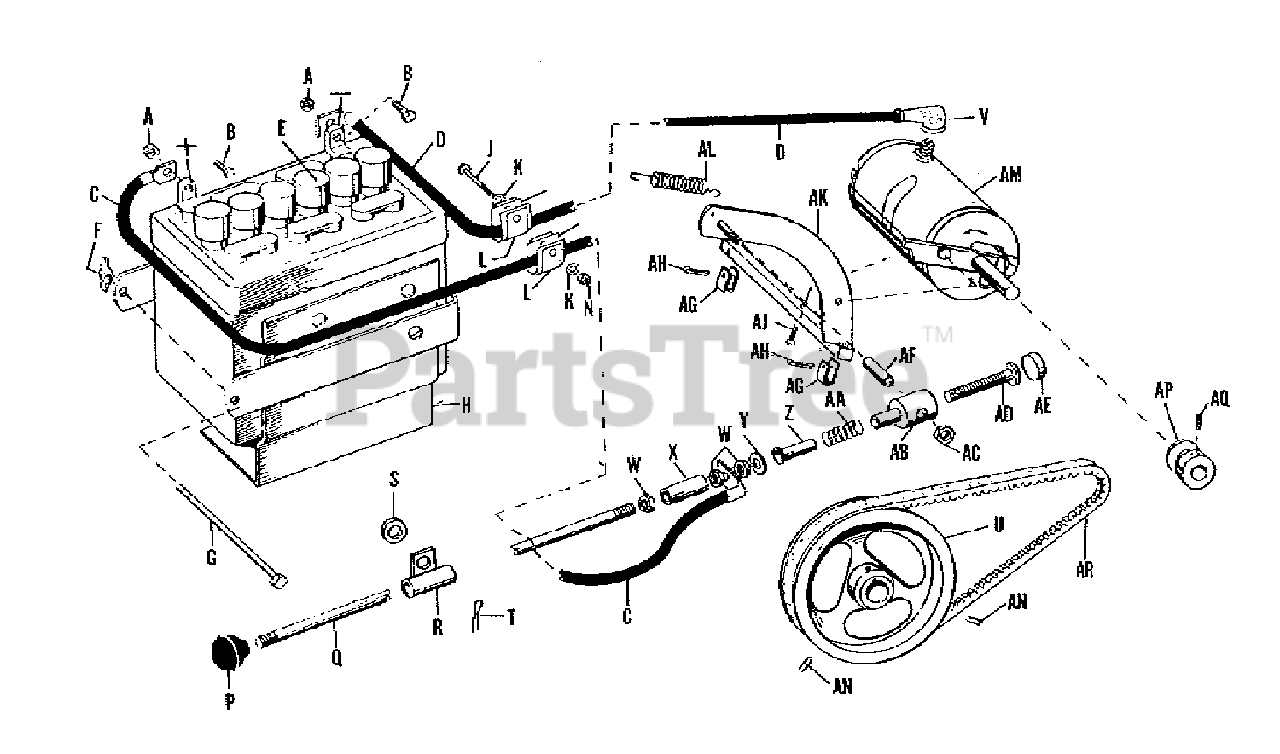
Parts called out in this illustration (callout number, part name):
A	NUT, Hex, Full, 1/4"-20 N.C. Reg.
B	SCREW, Hex Head Cap, 1/4"-20 NC x 5/8 Large
D	CABLE ASSEMBLY
E	BATTERY (PURCHASE FROM BAT. Mfg.)
F	NUT, Wing Lock, 1/4" 20NC
G	BOLT, Machine, 1/4" 20NC x 6" Large
H	BRACKET ASSEMBLY, Battery
J	SCREW, Round Head Machine, #10-24 X 1 1/2" Large
K	WASHER, Plain, 3/16 Standard
L	CLIP, Cable
M	LINING, Clip
N	NUT, Hex Lock, #10-24
P	KNOB, Starter
Q	ROD, Starter
R	GUIDE ASSEMBLY, Rod
S	WASHER, Plain, 3/8" Standard
T	PIN, Cotter
U	PULLEY, Engine
V	COVER, Terminal
W	NUT, Hex. Jam, 5/16"-18NC Reg.
X	INSULATOR
Y	WASHER, Plain, 5/16" Standard
AB	BODY, Switch
AC	NUT, Hex. Lock Full, 5/16-18NC Reg.
AD	BOLT, Contact
AE	PLUG, Switch Body
AG	STRAP, Motor Support
AH	PIN, Cotter
AJ	SCREW, Socket, 3/4"-20NC x 3/4" Large
AK	LEVER ASSEMBLY, Belt Tension
AM	MOTOR, Starter (See Note)
AN	SCREW, Hex. Socket Cup Point Set, 5/16"-18 NC x 1/2" Large
AP	PULLEY, Motor
AQ	SCREW, Hex Socket Cup Point Set, 1/4"-20 NC x 5/16" Large
AR	V" BELT, Starter 24" Large Cog Type`
